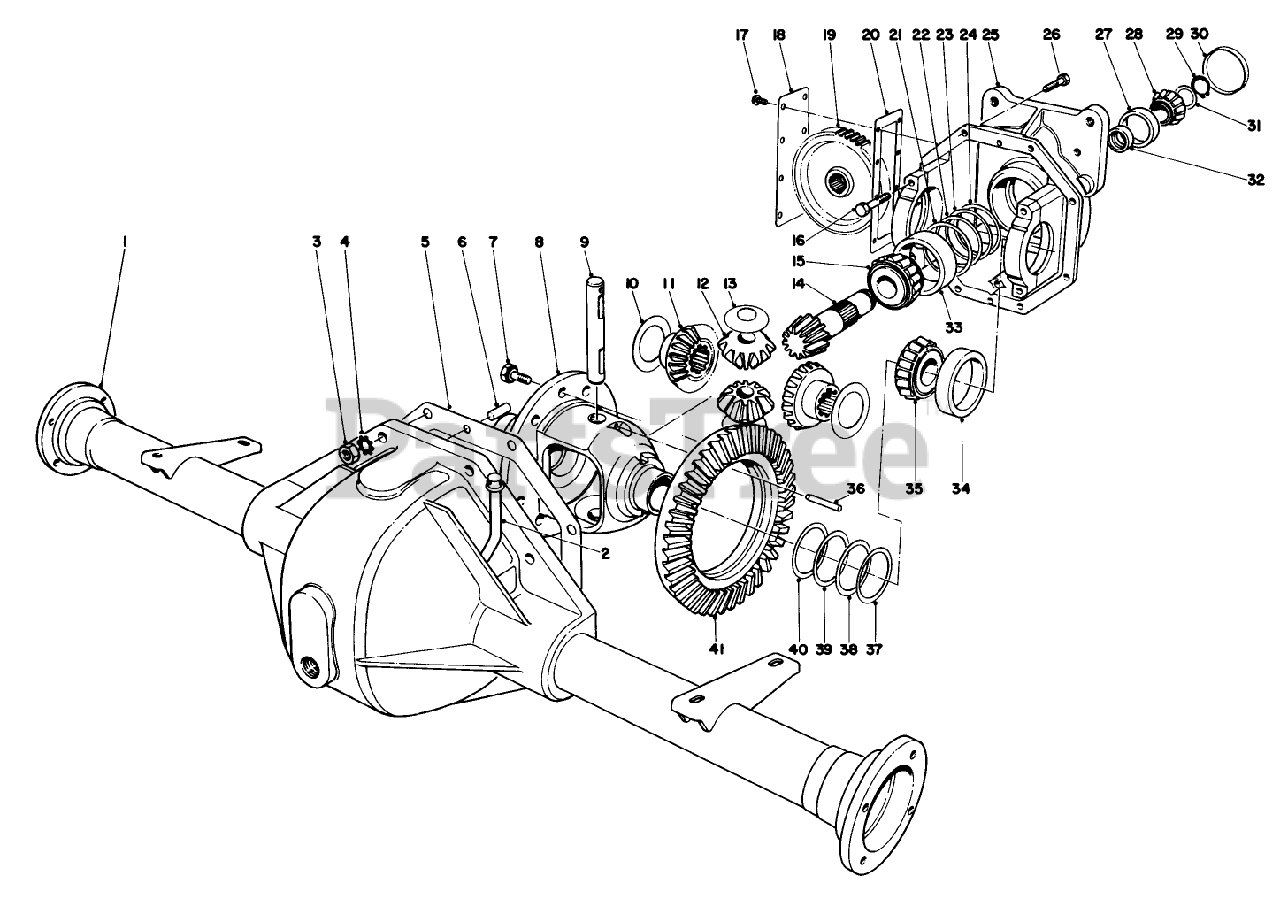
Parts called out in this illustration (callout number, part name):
1	Lower Housing & Tube Ass-y
2	Vent Assembly
3	NUT-HEX
4	WASHER-LOCK
5	HSG GASKET
6	PIN-DOWEL
7	SCREW-GEAR, DRIVE
8	CASE-DIFFERENTIAL
9	SHAFT-MATE, PINION
10	WASHER-THRUST
11	GEAR-DIFFERENTIAL
12	PINION-DIFFERENTIAL
13	WASHER-THRUST, PINION
15	ROLLER BRG CONE
16	SCREW-HH
17	SCREW
18	COVER-GEAR
19	Gear-Spur
20	GEAR COVER GASKET
21	REAR PINION BRG SHIM
22	BRG SHIM .005
23	BRG SHIM .010
24	BRG SHIM .030
25	Upper Housing Assembly (Incl. Ref. #16)
26	Screw
27	BEARING-CUP
28	BRG CONE
29	Retaining Ring
30	PLUG-CUP
31	FRT PINION BRG SHIM
32	SPACER-BEARING
33	ROLLER BRG CUP
34	CUP-BEARING, ROLLER
35	BEARING-ROLLER, CONE
36	Pin-Roll
37	SHIM-BEARING, DIFFERENTIAL (.003)
38	SHIM-BEARING, DIFFERENTIAL (.005)
39	SHIM-BEARING, DIFFERENTIAL (.010)
40	SHIM-BEARING, DIFFERENTIAL (.030)
41	Ring Gear
